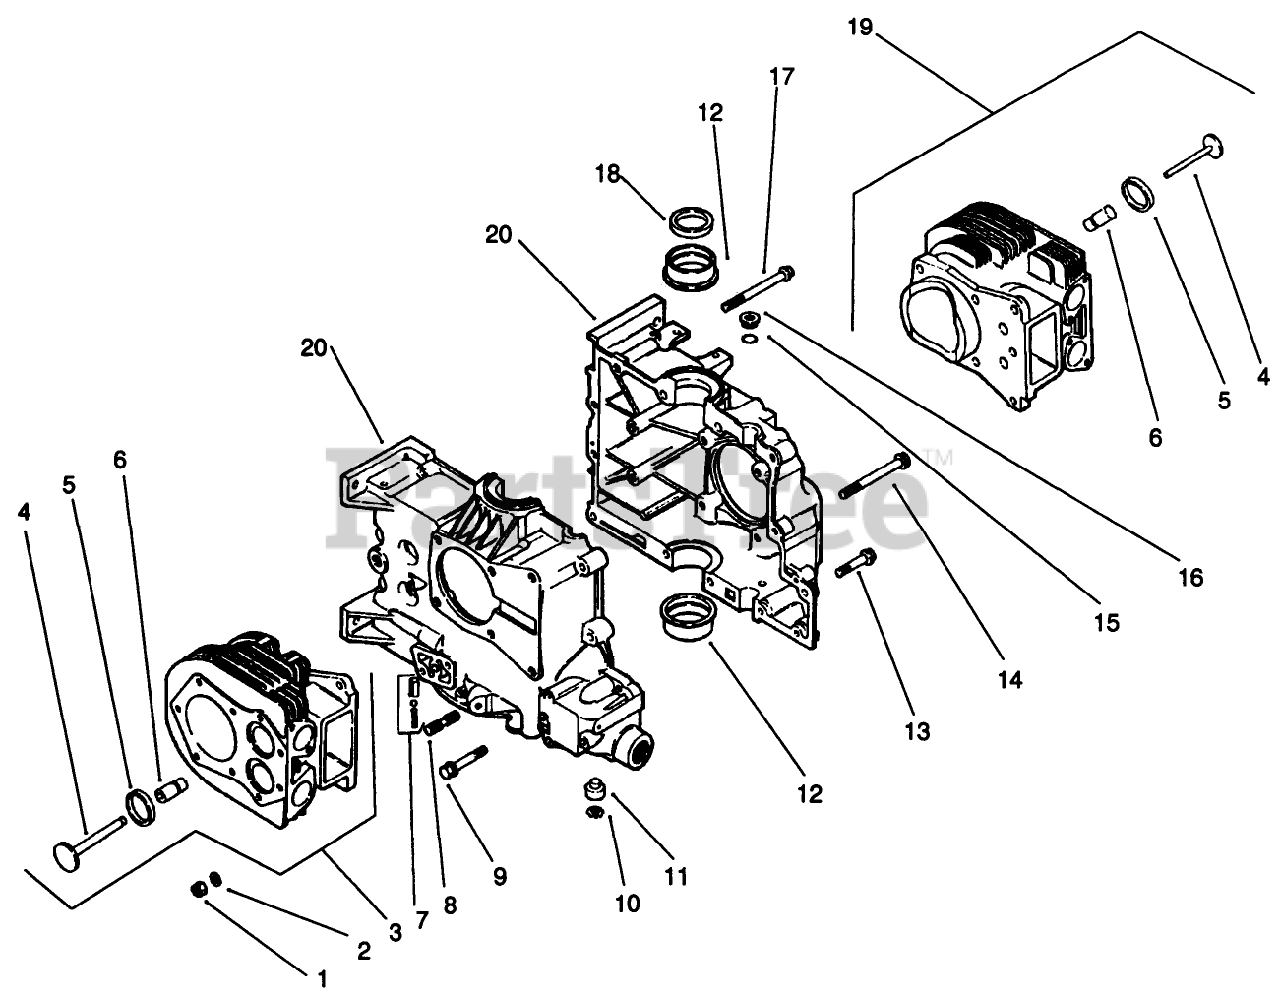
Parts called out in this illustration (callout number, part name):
2	Washer-Flat
3	Kit-#1 Cylinder Barrel (Incl. Ref. #4-6)
4	Valve-Exhaust
5	Inset-Valve Seat
6	Guide-Valve
7	Kit-Oil Relief
9	Screw-Hex Flange
10	Ring-Retaining
11	Shaft-Governor
12	Bearing-Sleeve
13	Screw-Hex Flange
14	Screw-Hex Flange
17	Screw-Hex Flange
18	Seal-ReAR Oil
19	Kit-#2 Cylinder Barrel (Incl. Ref. #4-6)
20	Crankcase Service with Short Block
